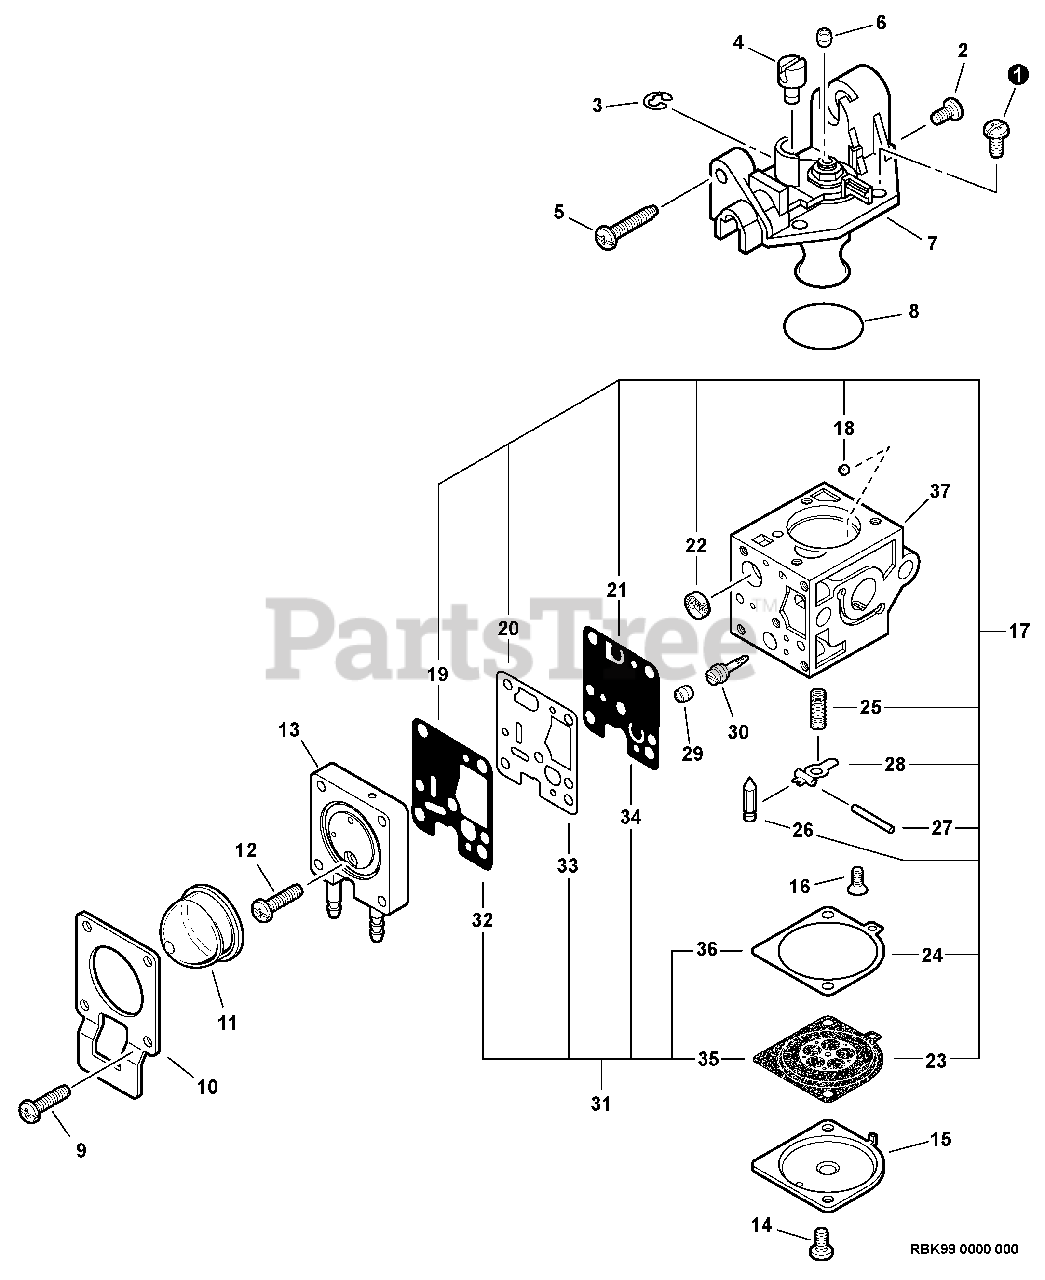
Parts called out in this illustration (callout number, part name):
3	RING, RETAINING
5	SCREW, THROTTLE ADJUST
7	ROTOR COVER ASSY
9	SCREW, RETAINER
10	RETAINER, PURGE BULB
11	BULB, PURGE
12	SCREW, PURGE BASE
13	BASE, PURGE
15	COVER, METERING
16	SCREW, METERING LEVER PIN
17	REPAIR KIT
18	GUIDE, ROLLER
19	DIAPHRAGM, PURGE
20	GASKET, PUMP
21	DIAPHRAGM, PUMP
22	STRAINER
23	DIAPHRAGM, METERING
24	GASKET, METERING
25	SPRING, METERING LEVER
26	VALVE, INLET NEEDLE
27	PIN, METERING LEVER
28	LEVER, METERING
30	NEEDLE - HIGH SPEED
31	DIAPHRAGM/GASKET KIT
32	DIAPHRAGM, PURGE
33	GASKET, PUMP
34	DIAPHRAGM, PUMP
35	DIAPHRAGM, METERING
36	GASKET, METERING
37	BODY, CARBURETOR
